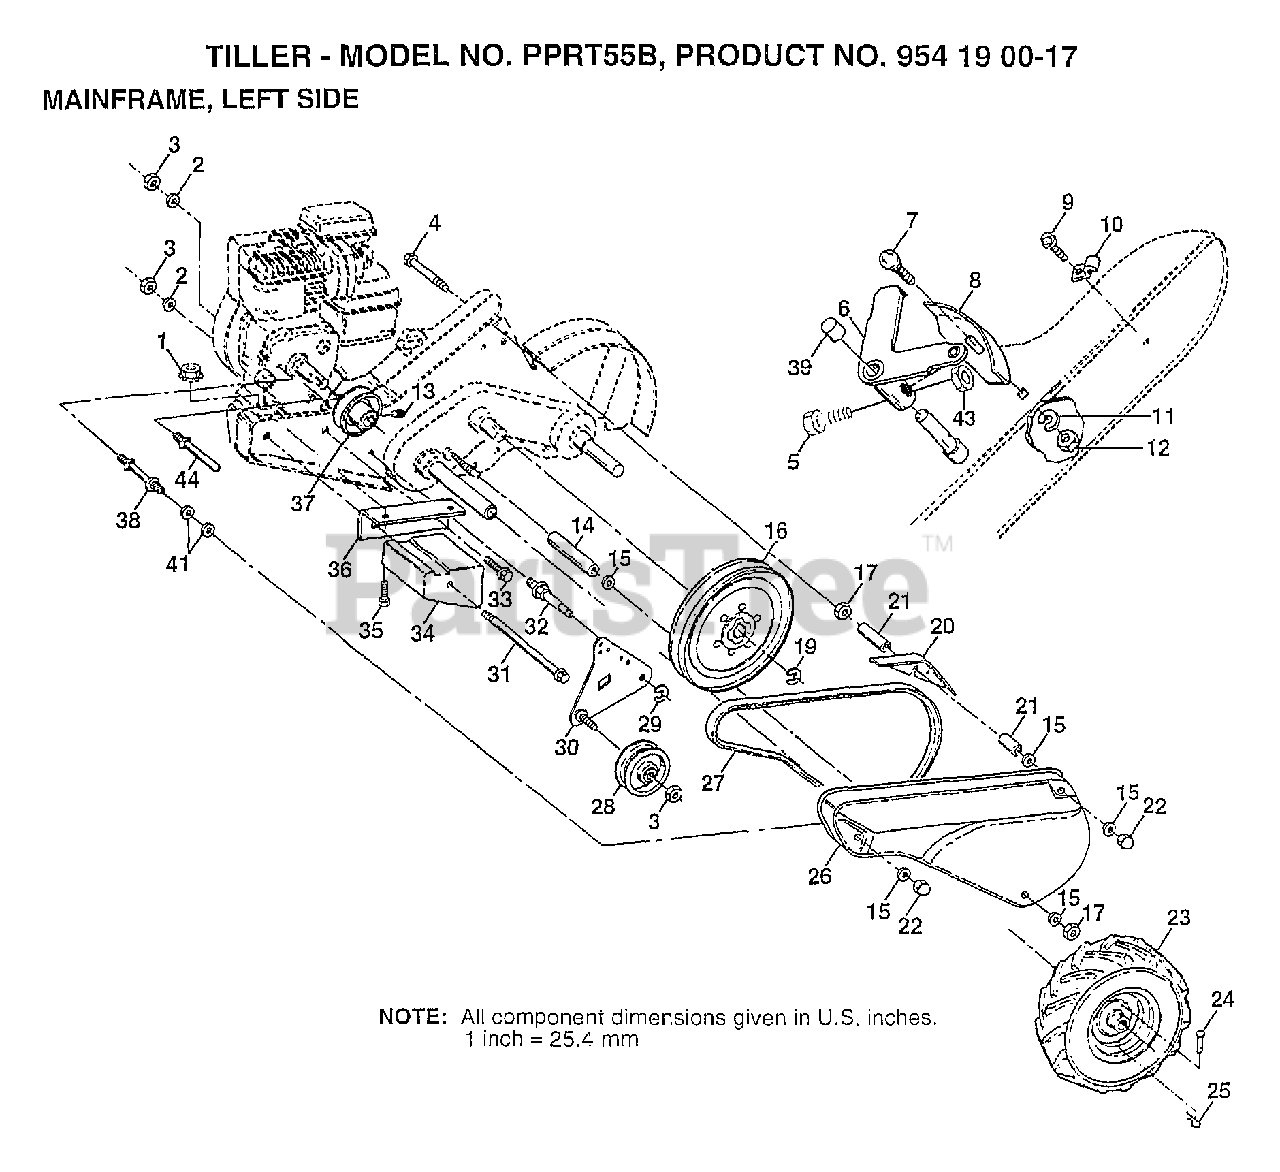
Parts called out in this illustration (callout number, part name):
2	LOCKWASHER
3	NUT.HEX.3/8-16UNC
4	BOLT TI
5	"SCREW-LEVER,SHI"
6	LEVER ASM CRT
7	BOLT
8	PANEL TI
10	CONDIUT CLIP T
11	LOCKWASHER
13	SET SCREW
14	SPACER
15	WASHER
16	SHEAVE.TRANS.
17	NUT.HEX.5/16-18
20	GUARD CRT
21	SPACER.SPLIT
22	NUT TI
23	TIRE TI
24	RIVET DRILLED
25	RETAINER M
27	BELT-V
28	PULLEY-IDLER TI
29	KLIP RING
30	BRACKET ASM IDLER
31	BOLT CRT
32	SHIFT ARM CRT
33	BOLT
34	COUNTERWEIGHT CRT
35	BOLT
36	BRACKET LH CRT
37	ENGINE PULLEY
38	STUD.GUARD.BELT
39	CAP PLUNGER BLACK
41	WASHER
43	LOCKNUT
44	KEEPER.BELT.ENGINE
